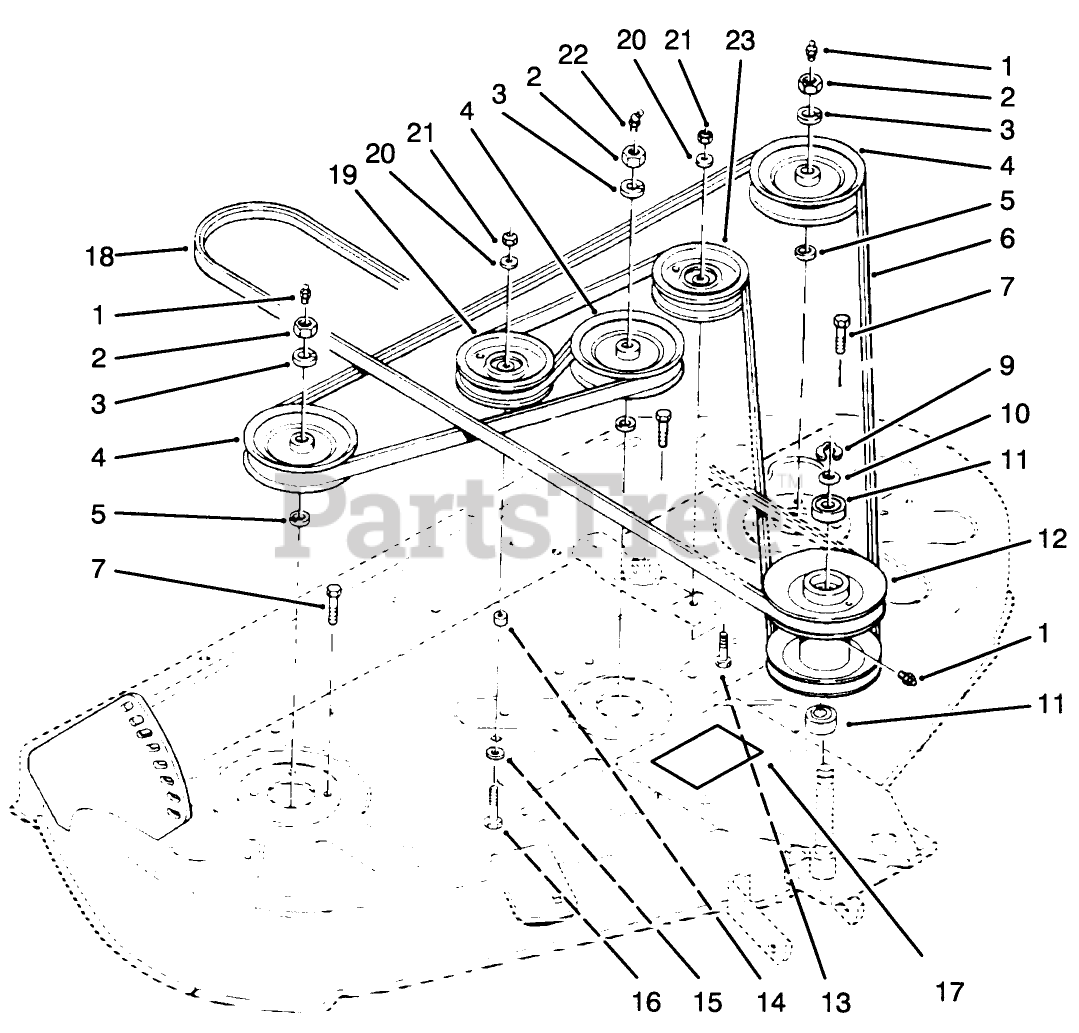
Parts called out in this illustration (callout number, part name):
1	FITTING-GREASE
2	NUT-JAM
3	WASHER-LOCK
4	PULLEY-SPINDLE
5	WASHER-FLAT
6	V-BELT
7	SCREW-HH
9	RETAINING RING
10	O RING
11	BEARING-BALL
12	PULLEY-COUNTER SHAFT
13	SCREW-HH
14	SPACER
15	WASHER
16	SCREW-HH
17	DECAL-BELT INSTALL
18	V-BELT
19	PULLEY-IDLER, FLAT
20	WASHER-FLAT
21	NUT-LOCK, NI
22	FITTING-GREASE
23	PULLEY-FLAT IDLER
